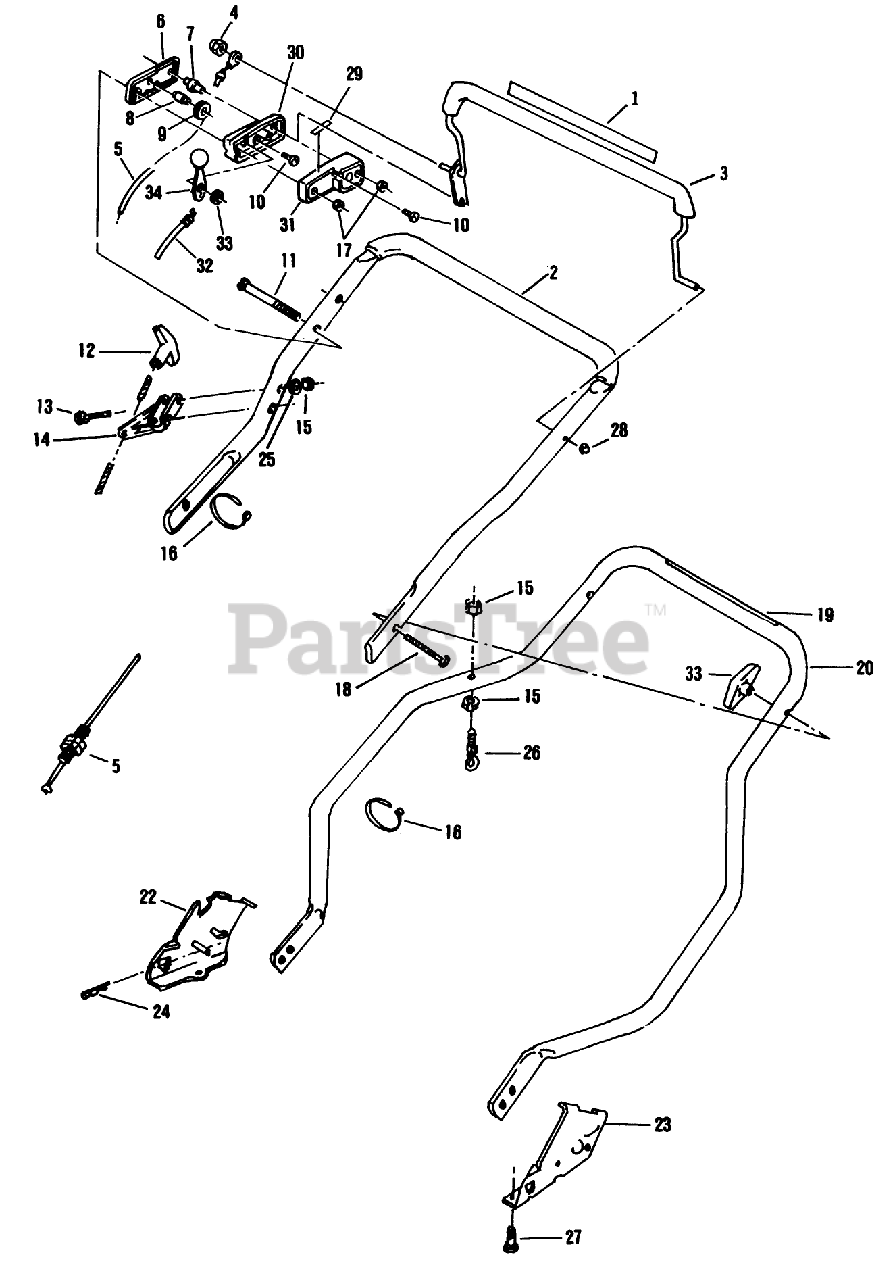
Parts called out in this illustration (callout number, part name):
4	NUT ACORN
5	CONTROL CABLE WES
7	COLUMN
8	PIN SKF
9	PULLEY PL
10	SCREW
11	SCREW
12	HANDLE START UM&D
15	LOCKNUT E
17	NUT C/LOCK E
18	BOLT QUALITY
21	NUT-WING
24	HAIR PIN
25	WASHER
26	EYE BOLT WAS MFG
27	SCREW
32	CABLE THROT WES
33	WASHER-SPRING
34	LEVER&KNOB AY WES
